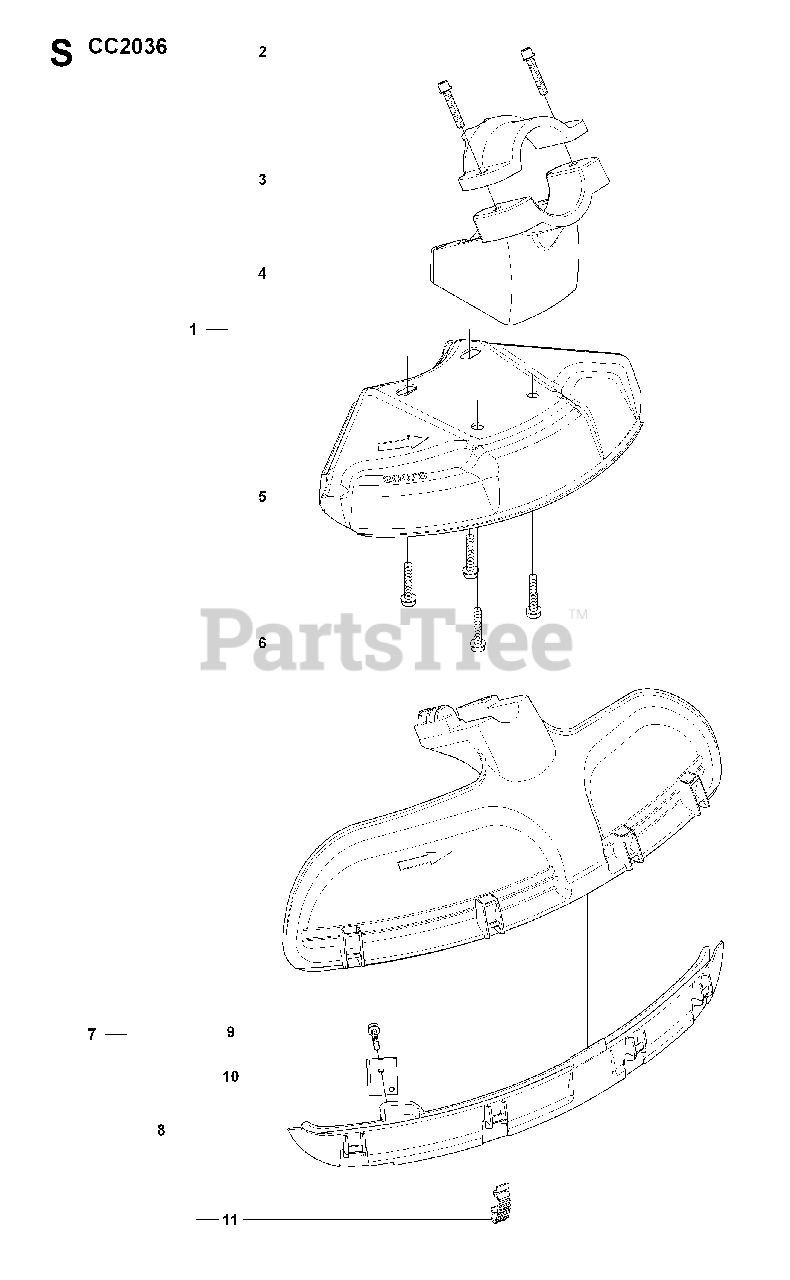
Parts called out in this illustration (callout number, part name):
1	%PROTECTOR
5	RP BLADE GUARD
7	SPLASH GUARD
10	LINE CUTTER
